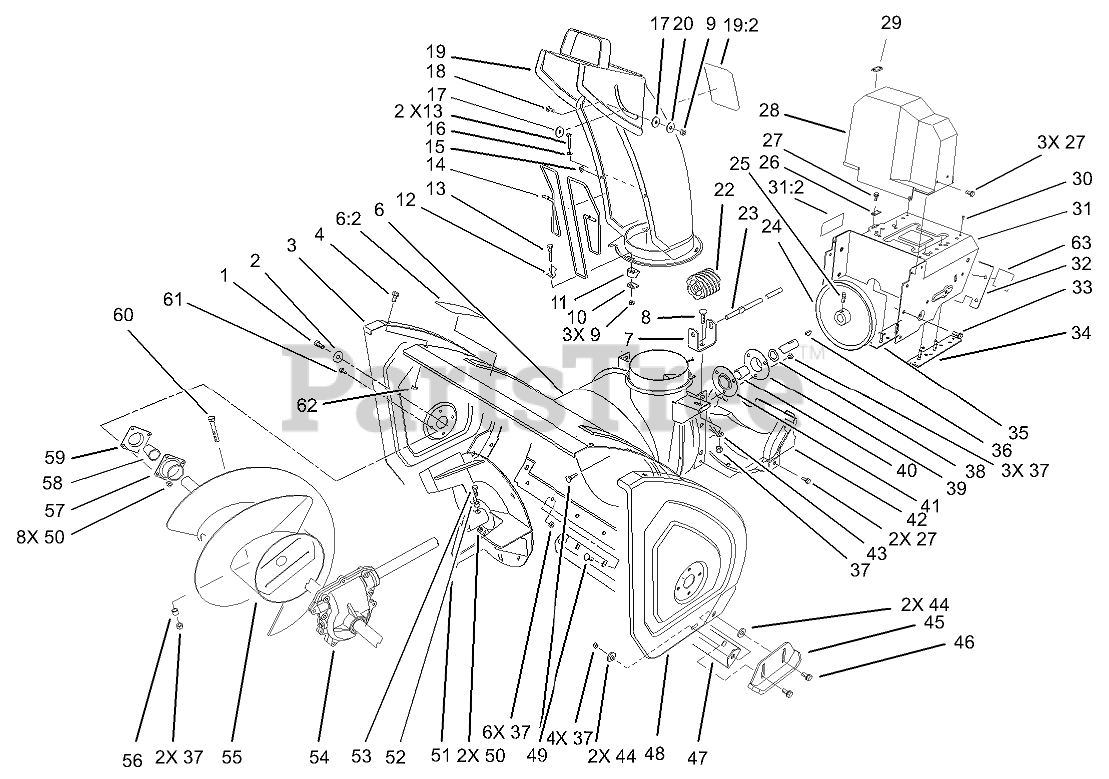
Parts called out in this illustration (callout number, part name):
1	SCREW-HH
2	WASHER
3	PLATE-SIDE, RH
4	SCREW-HHF
6	AUGER HOUSING ASM
6:2	DECAL-WARNING, AUGER
7	BRACKET-WORM, CHUTE
8	BOLT-CARR
9	NUT-LOCK, NI
10	PLATE-RETAINER, CHUTE
11	RETAINER-CHUTE
12	CLIP-GUARD, CHUTE
13	SCREW-HSH
14	GUARD-CHUTE
15	NUT-PUSH
16	WASHER-FLAT
17	WASHER-PLASTIC
19	CHUTE
19:2	DECAL-DANGER (only on: 38078)
20	WASHER-FLAT
22	GEAR-WORM
23	ROD-CHUTE, LOWER
24	PULLEY-IMPELLER
25	SCREW-SET, SQH
26	RETAINER-CABLE
27	SCREW-HWH
28	COVER-BELT, UPPER
29	COVER-CABLE
30	RIVET-POP
31	ENGINE FRAME ASM
31:2	DECAL-WARNING
32	COVER-FRAME, ENGINE
33	SCREW-HWHTF
34	LH FRAME PLATE ASM
35	RH FRAME PLATE ASM
36	KEY-WOODRUFF
37	NUT-LOCK, NI
38	WASHER-THRUST
39	FLANGE-CUP, BEARING
40	BEARING-BALL
41	FLANGE-CUP, BEARING
42	COVER-BELT, LOWER
43	WASHER-PLAIN
44	WASHER
45	SKID ASM
46	SCREW-HHF
47	BLADE-SCRAPER
48	PLATE-SIDE, LH
49	SCREW-CARR
50	NUT-LOCK, NI
51	IMPELLER-4 BLADE
52	SPACER
53	SCREW-HHF
54	LH AUGER GEARCASE ASM
55	AUGER, RH
56	SPACER-HUB, AUGER
57	BEARING-FLANGE, FRONT
58	BEARING
59	BEARING-FLANGE, REAR
60	SCREW-HH
61	SCREW-HH
62	NUT-LOCK, NI
63	DECAL
